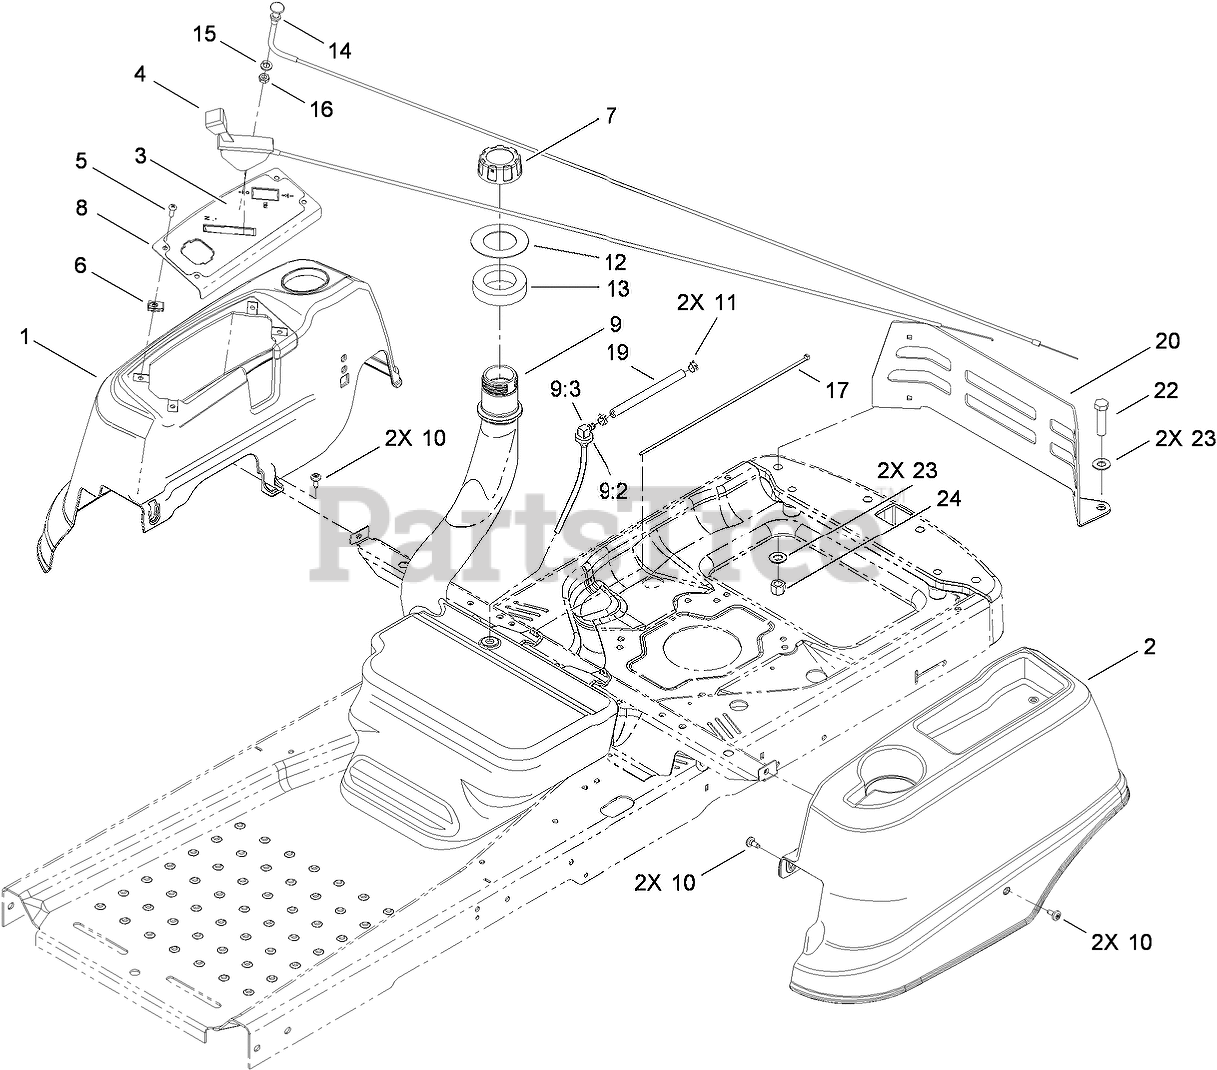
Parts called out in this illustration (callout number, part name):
1	POD-RH
2	POD-LH
3	DECAL-PANEL, CONTROL
4	CABLE-THROTTLE
5	SCREW-PRH
7	CAP-GAS
8	PANEL-CONTROL
9	FUEL TANK ASM
9:2	BUSHING
9:3	FITTING-90 DEGREE
10	SCREW-SHOULDER
11	CLAMP-HOSE
12	WASHER-RUBBER
13	SEAL-FOAM
14	CABLE-CHOKE
15	WASHER-LOCK
16	NUT-HJ
17	TIE-CABLE
19	HOSE-FUEL
20	GUARD-ENGINE
22	SCREW-HH
23	WASHER-FLAT
24	NUT-LOCK, NI
